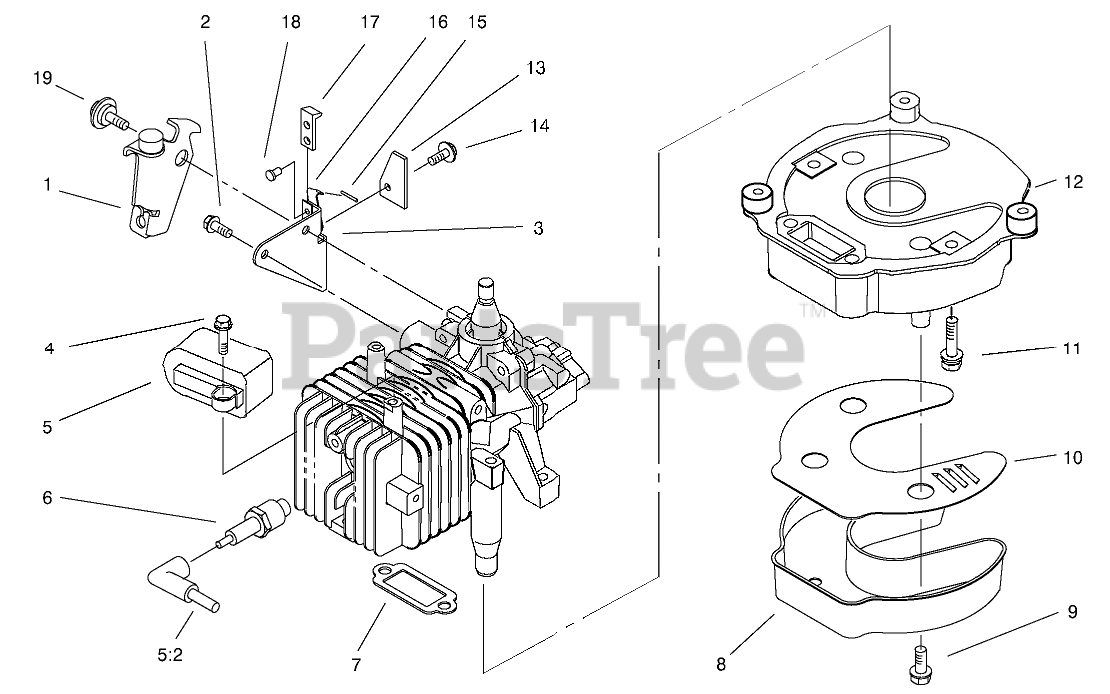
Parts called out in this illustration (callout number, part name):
1	PLATE-BRAKE
2	SCREW
3	PLATE-BRAKE
4	SCREW
5	MODULE-IGNITION
5:2	LEAD-TENSION, HIGH
6	SPARK PLUG
7	GASKET-EXH. VF
8	COVER-MUFFLER V BLACK
9	SCREW
10	BAFFLE-MUFFLER
11	SCREW V
12	PLATE-MUFFLER V
13	STOP-GROUND STRAP
14	SCREW
15	ELECTRICAL LEAD ASM
16	STRAP-GROUND
17	STRAP-INSULATION
18	RIVET-PLASTIC
19	SCREW-SHOULDER
